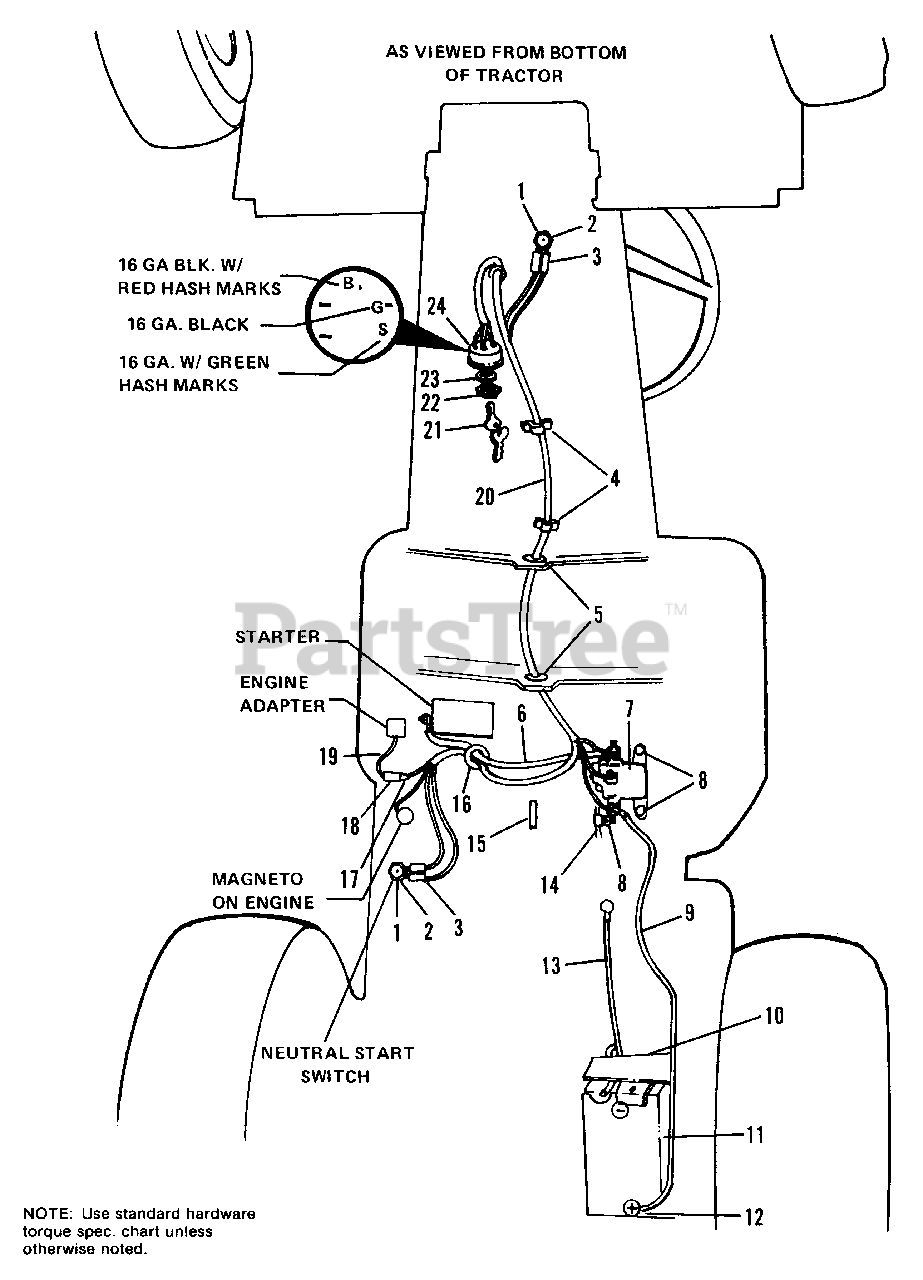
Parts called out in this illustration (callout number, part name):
1	SWITCH, Safety
2	PALNUT, 9/16-18
3	CONNECTOR. Body
4	CLIP, Wire
6	CABLE ASSY. (Solenoid to Starter)
8	SCREW, Hex, Washer Hd., Taptite, 1/4-20 x 3/8
9	CABLE ASSY. (Battery to Solenoid)
10	SUPPORT ASSY., Battery
11	BATTERY & CLIP ASSY.
12	STRAP, Rubber
13	CABLE ASSY. (Battery neg. to ground)
17	SCREW, Pan Hd., Phillips, Taptite, #8-32 x 3/4
19	WIRE ASSY.
20	HARNESS, Wiring
21	KEY & RING ASSY.
22	NUT, Special
23	LOCKWASHER, Int. 5/8
24	SWITCH, Ignition
